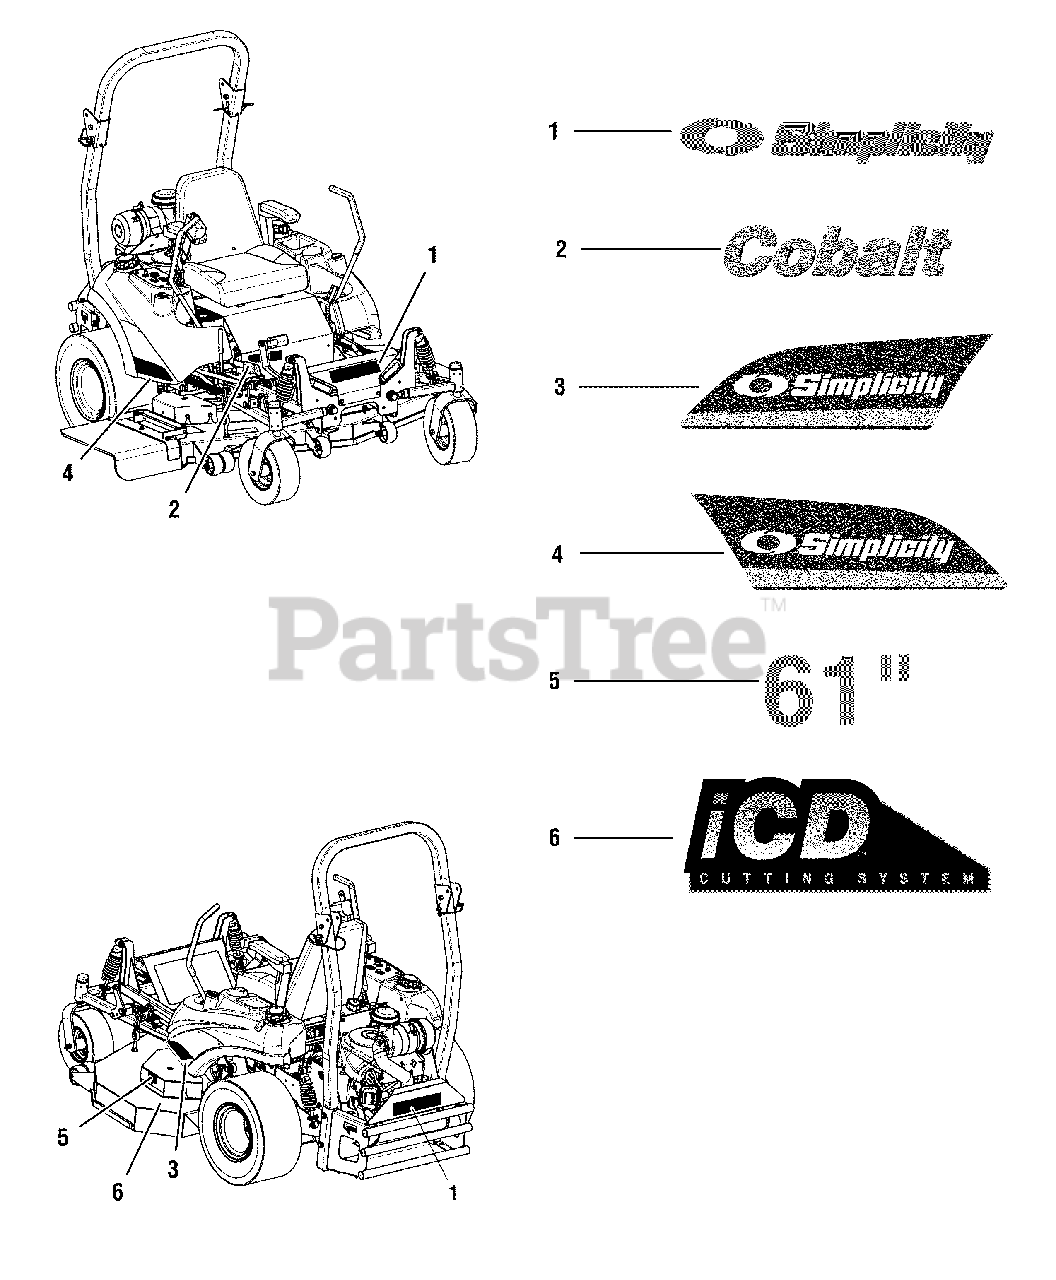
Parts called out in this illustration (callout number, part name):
1	DECAL, SIMPLICITY LOGO
2	DECAL, COBALT
3	DECAL, COBALT, BADGE, LH
4	DECAL, COBALT, BADGE, RH
5	DECAL, 61
6	DECAL, iCD CUTTING SYSTEM
